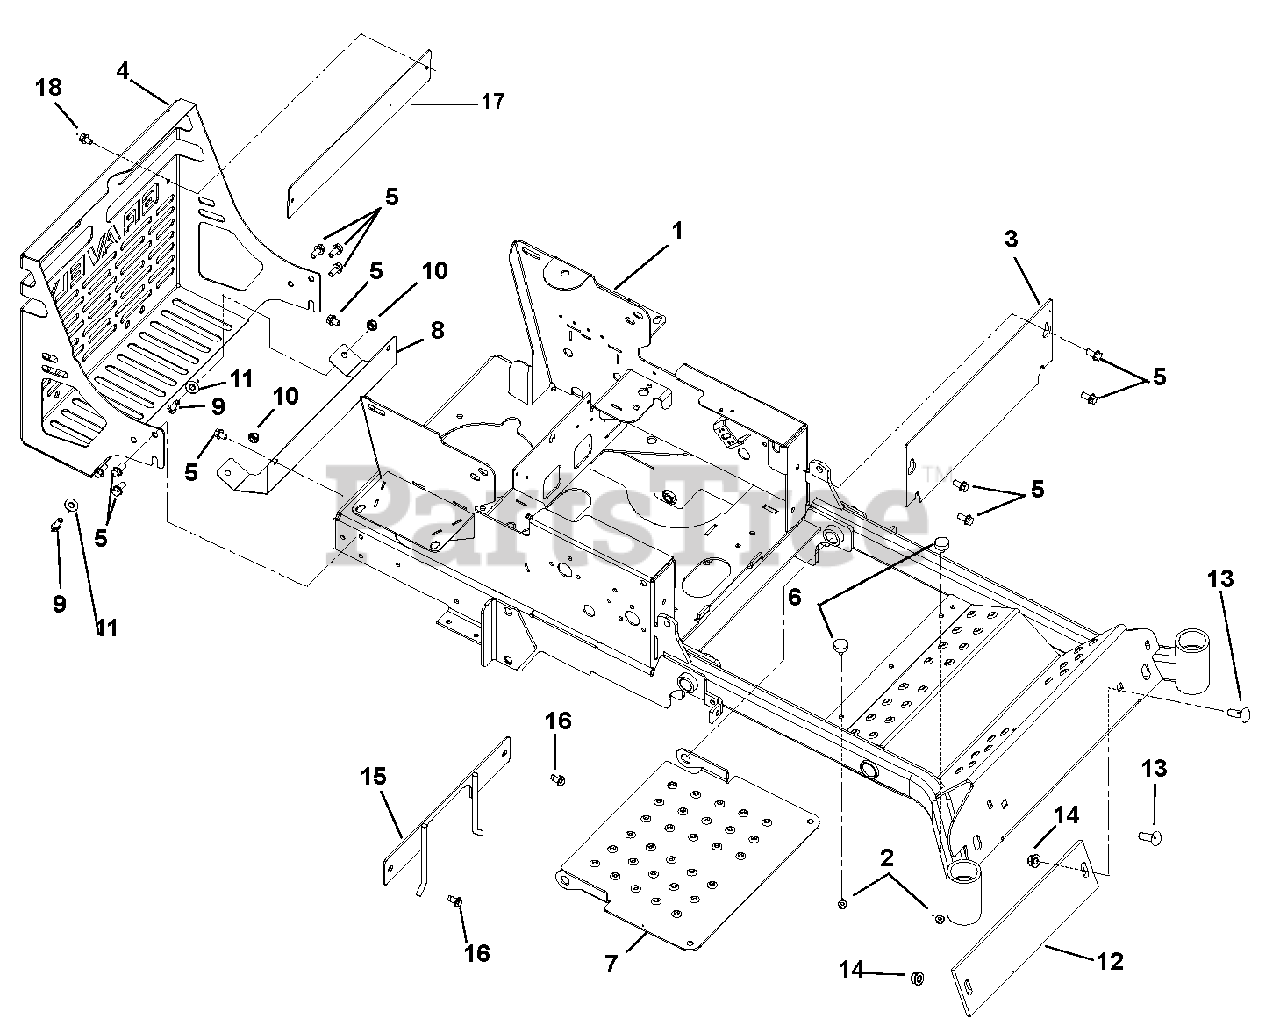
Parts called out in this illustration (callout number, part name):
1	Weldment, 44"HD Frame
2	Nut, Spin Lock Flange .312-18
3	Kick Plate
4	Bumper,
5	Screw, Tapping .38-16 x .75 Hex Washer Head
6	Bumper, Rubber
7	Panel, Inspection
8	Heat Shield
9	Bolt, Hex .38-16 x 1.00 Grade 5
10	Nut, Nyloc Flange .38-16
11	Washer, Flat Steel .438 x 1.00 x .083
12	Counterweight CZ Front
13	Bolt, Round Head Square Neck .50-13 x 1.25 Grade 5
14	Nut .50-13 Nyloc Flange
15	Weldment, PTO Belt Finger
16	Screw, Tapping .38-16 x .75 Hex Washer Head Thread
17	Bumper Backing Plate
18	Screw, Tapping .25-20 x .50 Hex Washer Head
